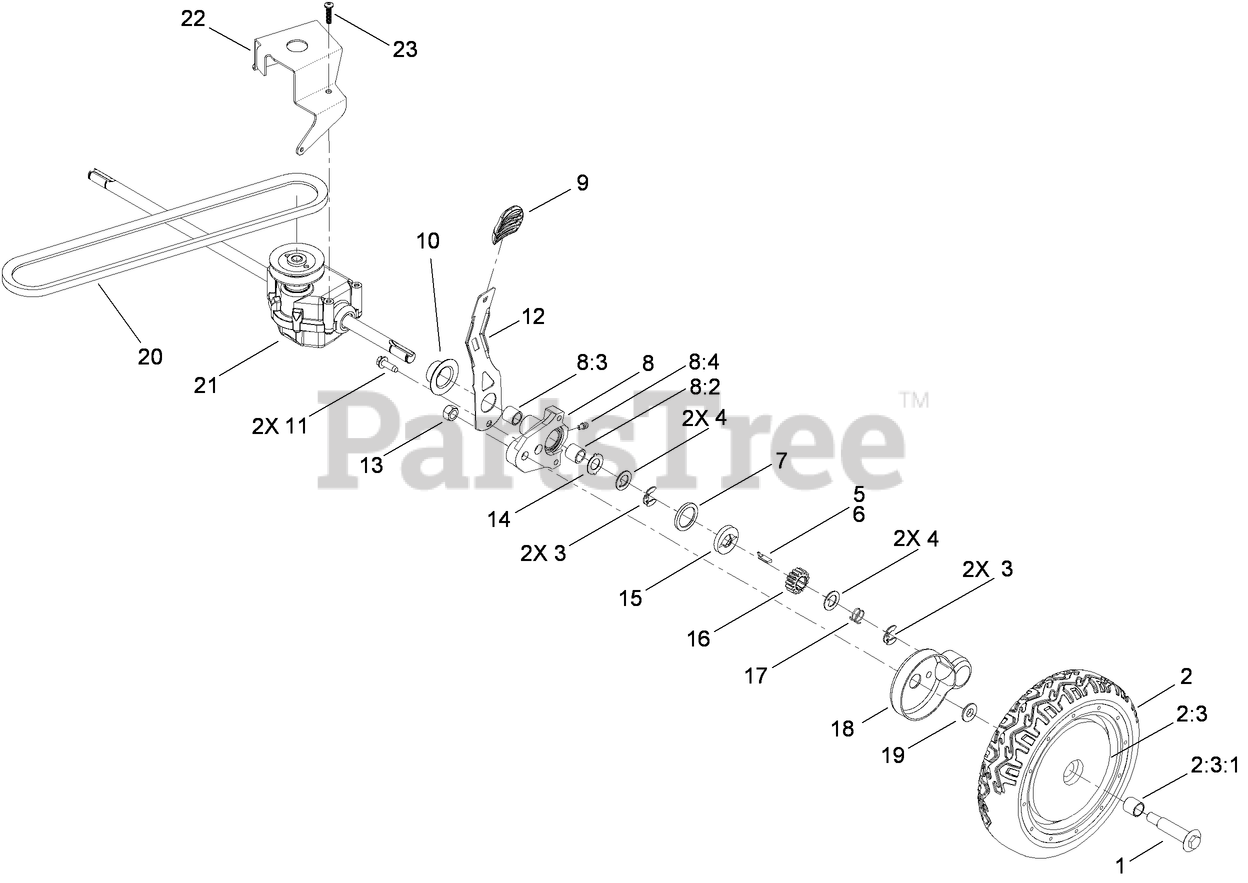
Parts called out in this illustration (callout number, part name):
1	BOLT-SHOULDER
2	WHEEL GEAR ASM
2:3	Loose Parts Package
2:3:1	BUSHING
3	RING-RETAINING,CLIP
4	WASHER-THRUST, KEYED
6	KEY-ROCKING, LH
7	RING-FRICTION
8	PIVOT ARM ASM
8:2	BUSHING
8:3	BUSHING
8:4	FITTING-GREASE
9	KNOB-LEVER, HOC
10	CAP-END
11	SCREW-HWHTF
12	ARM-SPRING
13	LOCKNUT
14	WASHER-ARM, PIVOT
15	WASHER-CLUTCH
16	GEAR-PINION
17	SPRING-COMPRESSION
18	COVER-WHEEL
19	SPACER-COVER, WHEEL
20	V-BELT
22	BRACKET-TRANSMISSION
23	SCREW-PLASTITE
